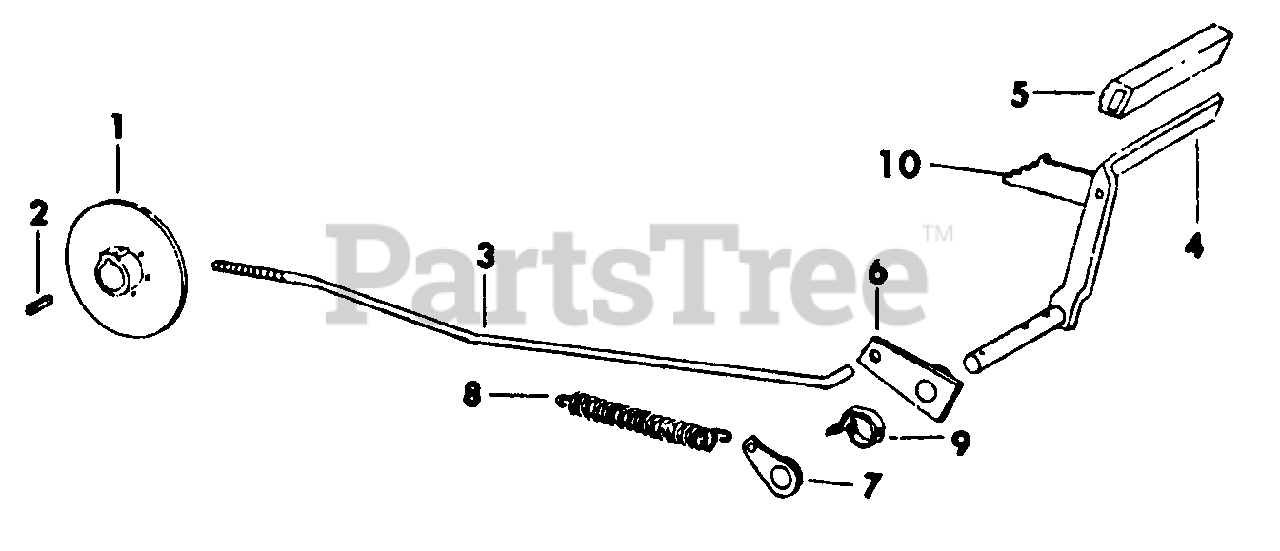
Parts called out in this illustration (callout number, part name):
1	Disc and Hub Assy
2	Key, 3/16 X 3/4 SAE 9 Woodruff
3	Rod, Brake
4	Pedal Assy, Clutch and Brake
5	Pad, Pedal
6	Lever Assy, Foot Pedal Brake
7	Brake Assy
8	Spring, Extension
9	Not used in this application
10	Ratchet, Brake Lock
